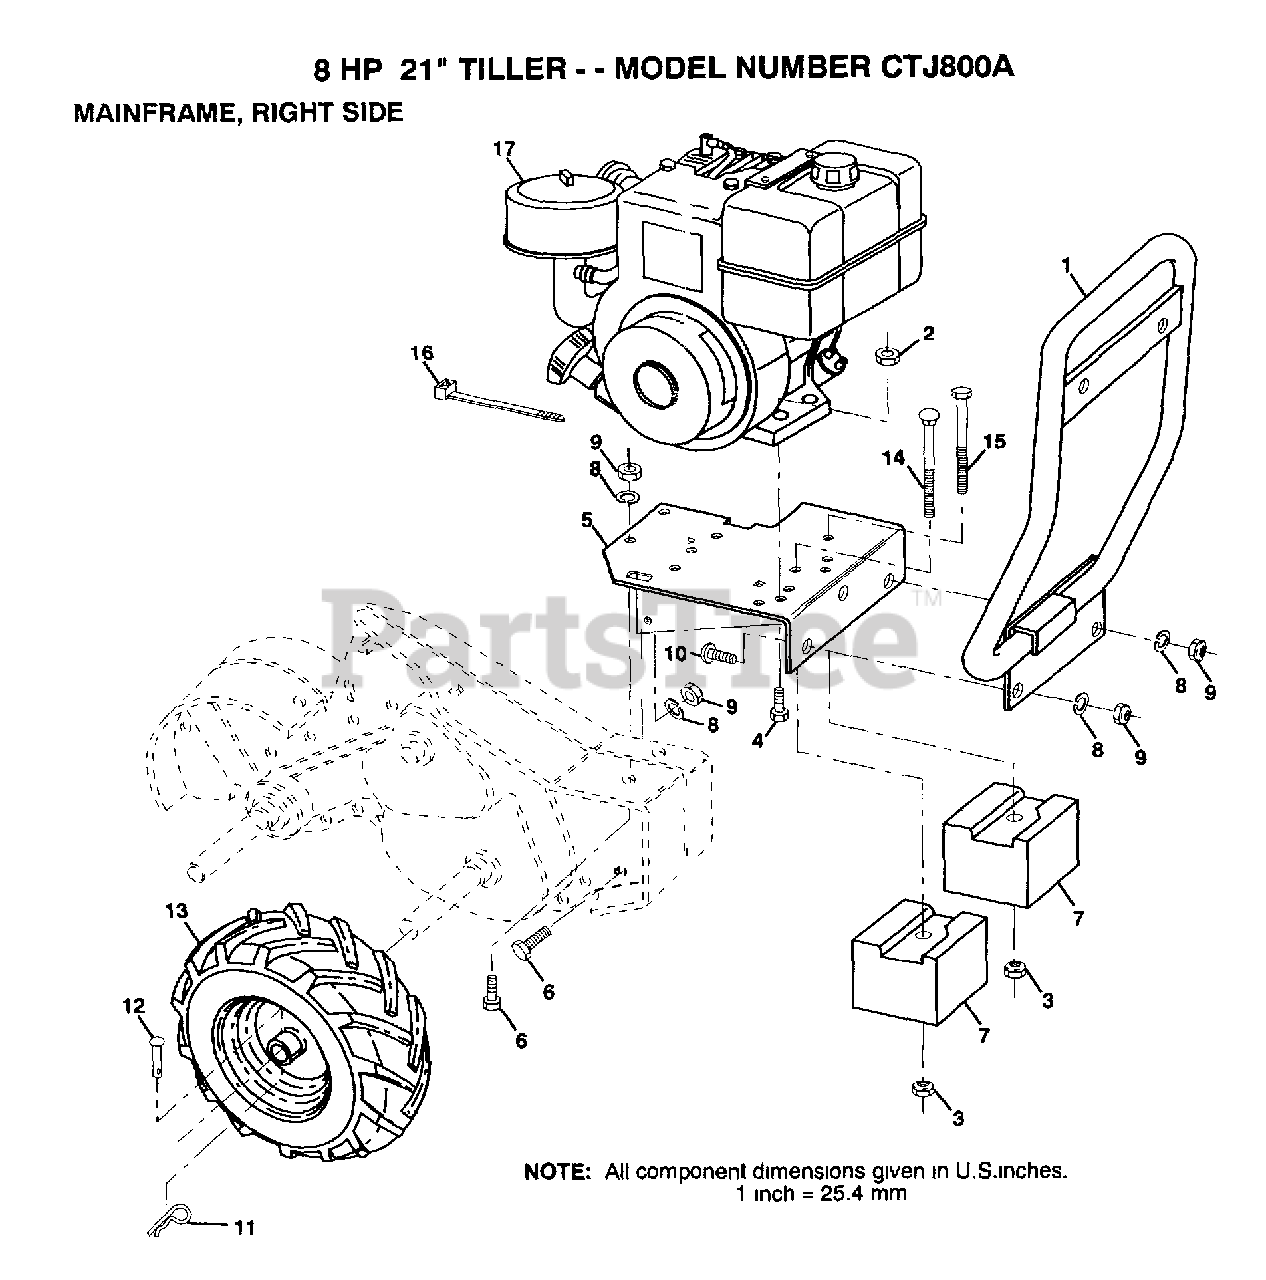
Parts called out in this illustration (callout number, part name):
1	BUMPER.ASM
4	BOLT
5	"ASM. ENGINE, BASE"
6	BOLT
7	COUNTERWEIGHT CRT
8	LOCKWASHER
9	NUT.HEX.3/8-16UNC
11	SPRING.RETAINER
12	RIVET.PAN HD.1.75
13	TIRE TI
14	BOLT CRT
15	BOLT.3/8-16X4.5
16	TIE CABLE CRT
